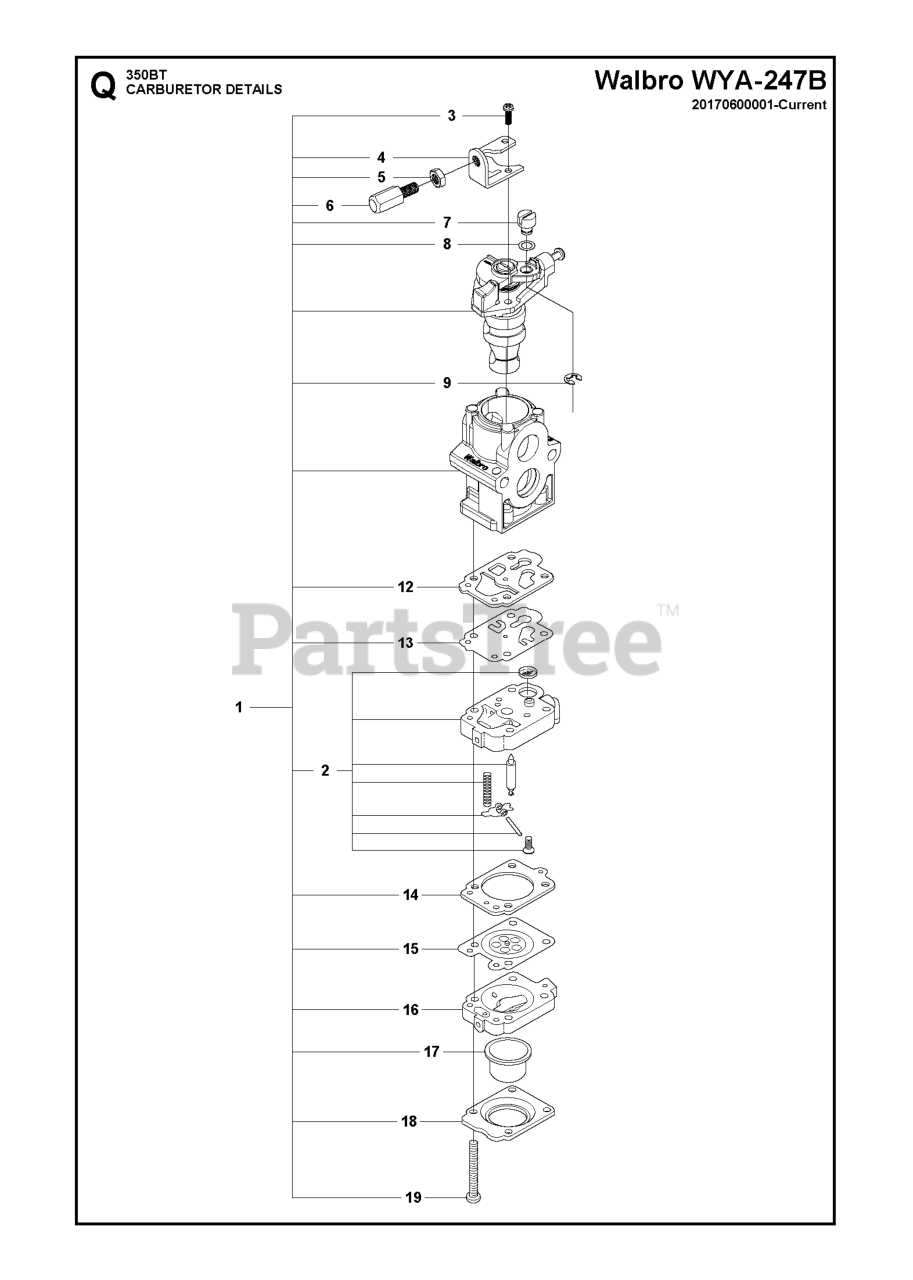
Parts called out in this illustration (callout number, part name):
1	CARBURETTOR
2	BODY-A-PUMP
5	NUT
6	ADJUSTER
